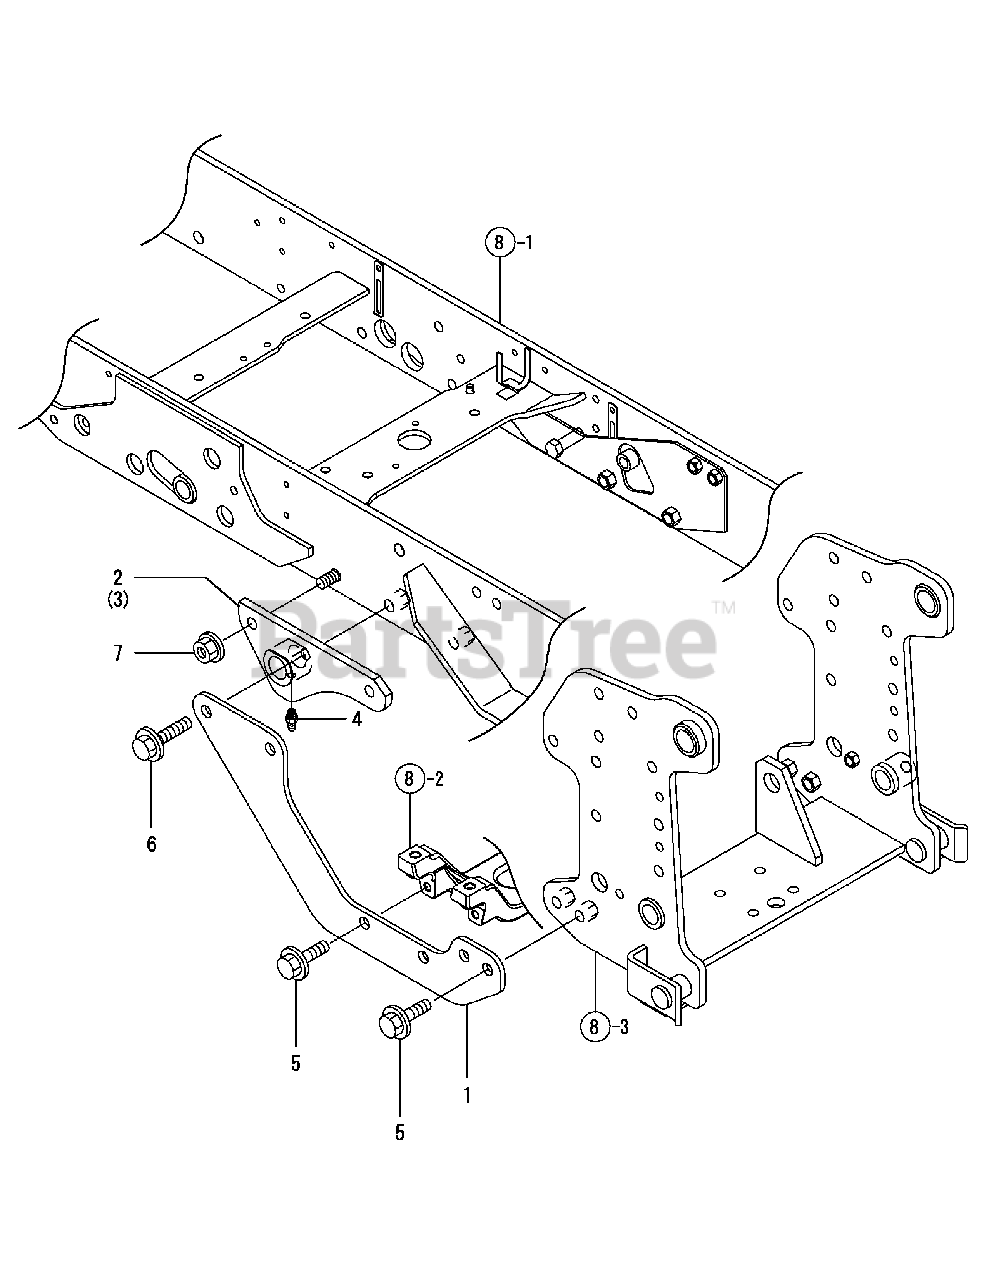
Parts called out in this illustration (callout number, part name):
1	PLATE, SUPPORT UNDER
2	PLATE ASSY, L MOWER
3	PLATE ASSY, R MOWER
4	NIPPLE PT1/8, GREASE
5	BOLT M12X 25 PLATED
6	BOLT, M12X 40 PLATED
